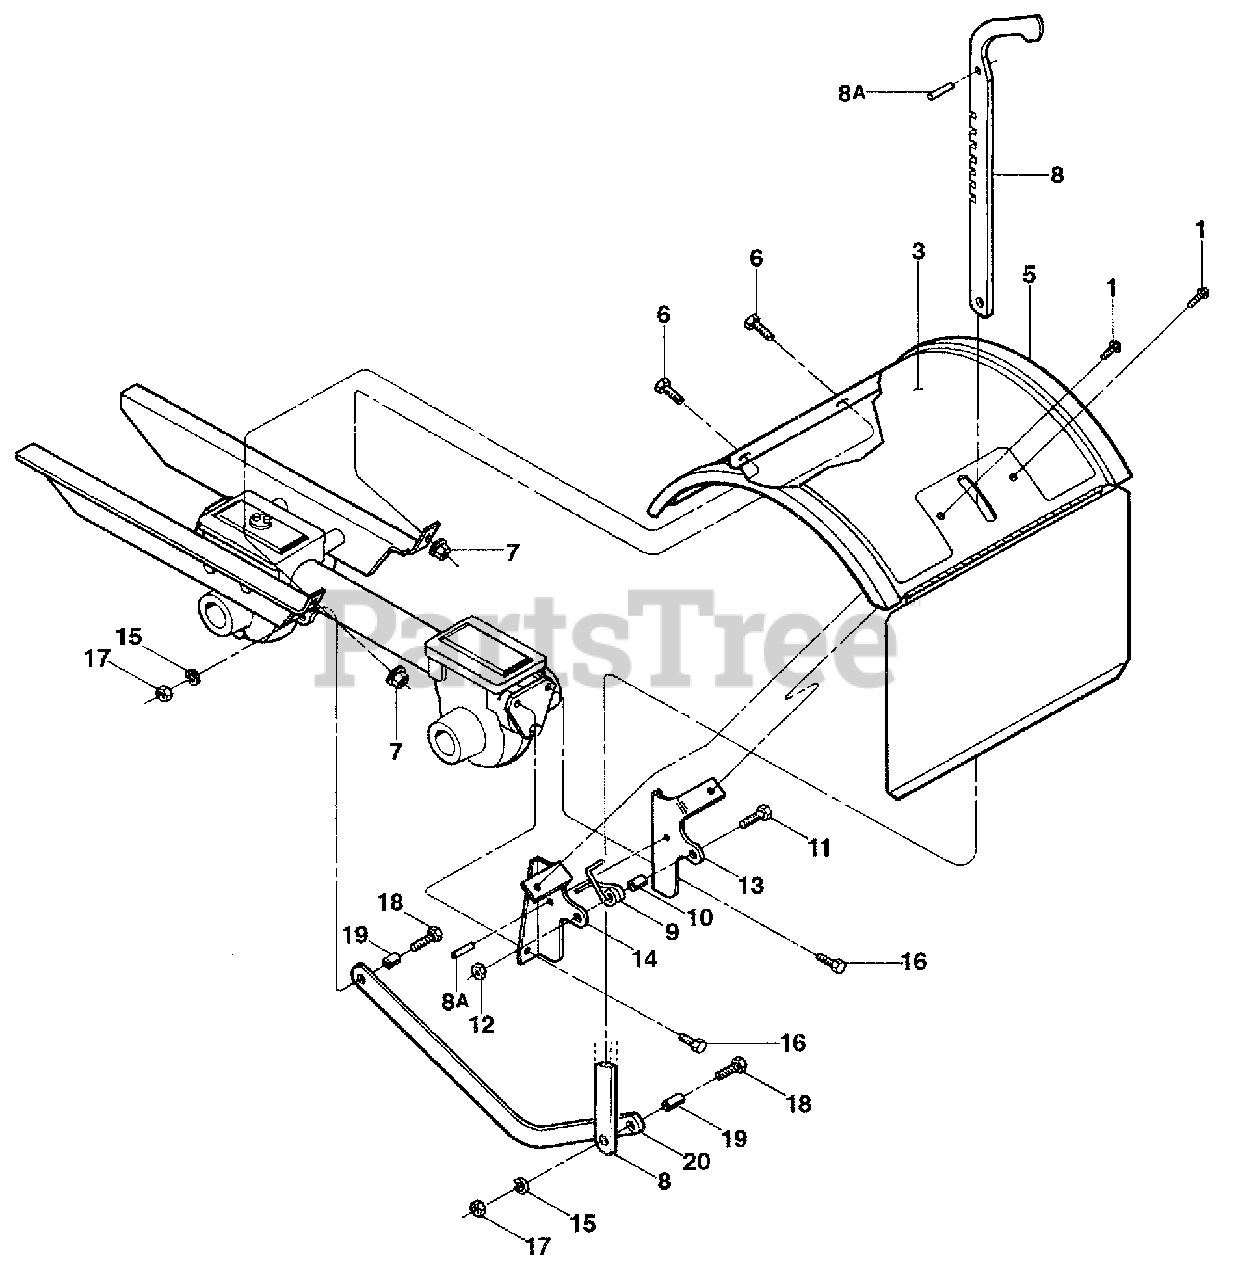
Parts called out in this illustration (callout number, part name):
1	Hex Hd. Flange Screw, Self-Tapping, 1/4-20 x 1/2
3	Decal, Hood
5	Tine Hood
6	Hex Hd. Screw, 5/16-18 x 1/2
7	Hex Flange Lock Nut, 5/16-18
8	Depth Regulator Lever
8A	Spirol Pin
9	Spring, Depth Regulator
10	Spacer
11	Hex Hd. Screw, 1/4-20 x 1
12	Hex Lock Nut, 1/4-20
13	Hood Bracket, Right Hand
14	Hood Bracket, Left Hand
15	Lock washer, 5/16
16	Hex Hd. Flange Screw, 5/16-18 x 1
17	Hex Nut, 5/16-18
18	Hex Hd. Screw, 5/16-18 x 1-1/4
19	Bushing
20	Drag Bar
